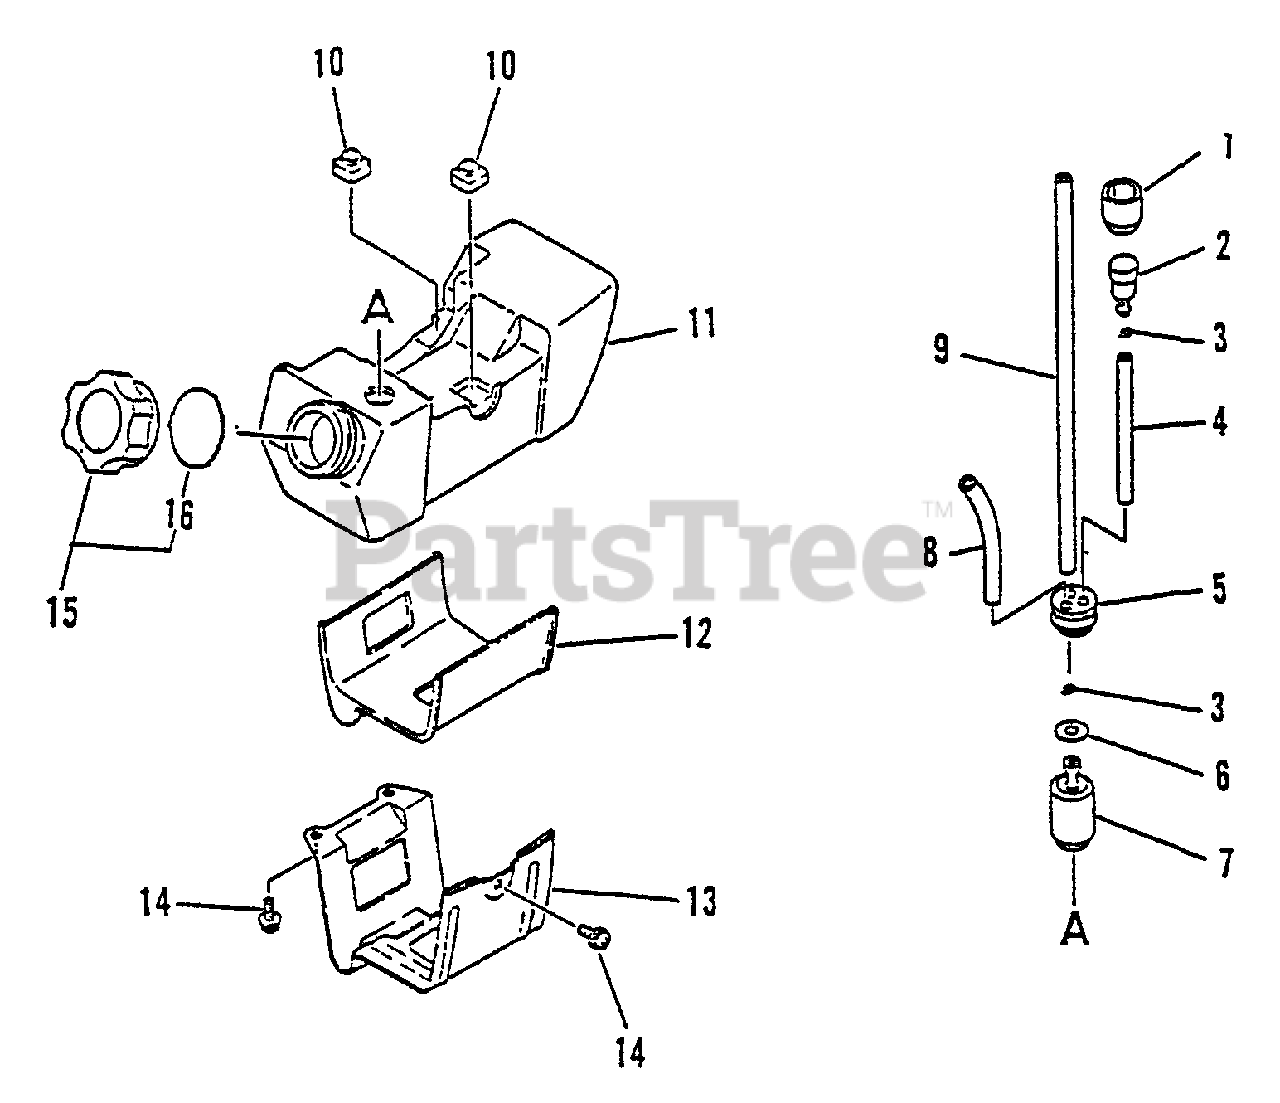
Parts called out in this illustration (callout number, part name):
1	HOLDER, VENT
2	VENT ASSY
4	PIPE, FUEL VENT 3×5×60
5	GROMMET, FUEL
6	WASHER 5.5×12×0.8
7	FILTER, FUEL
8	PIPE, FUEL RETURN 3×6×90 MM CLEAR
9	PIPE, FUEL 3x-5x-180
10	CUSHION
11	TANK, FUEL
12	CUSHION
13	GUARD, FUEL TANK
14	SCREW 5×10
15	CAP ASSY
16	GASKET, FUEL CAP
